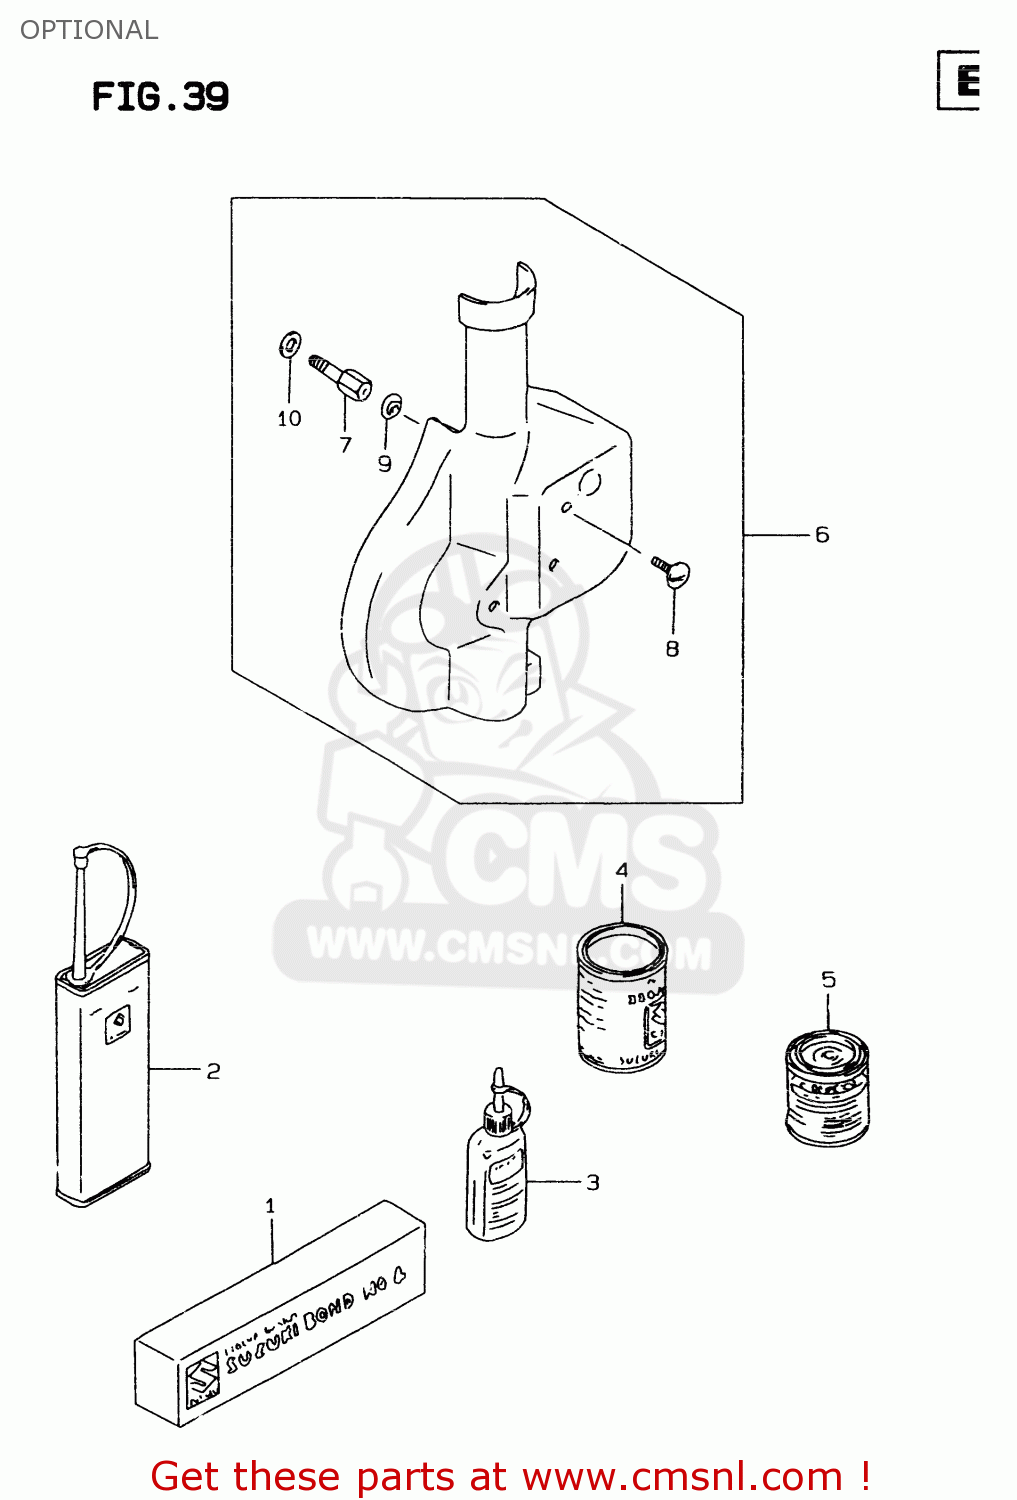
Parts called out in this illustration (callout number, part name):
1	BOND 1104
2	THREAD LOCK NO.1401 CLEAR 200G
3	THREAD LOCK NO
4	GREASE(C)EP2 LITHIUM 150G
5	PAINT,BLACK
6	COVER SET,FRONT DISC
7	BOLT,FRONT DISC COVER
8	SCREW(6X14)
9	WASHER
10	WASHER
